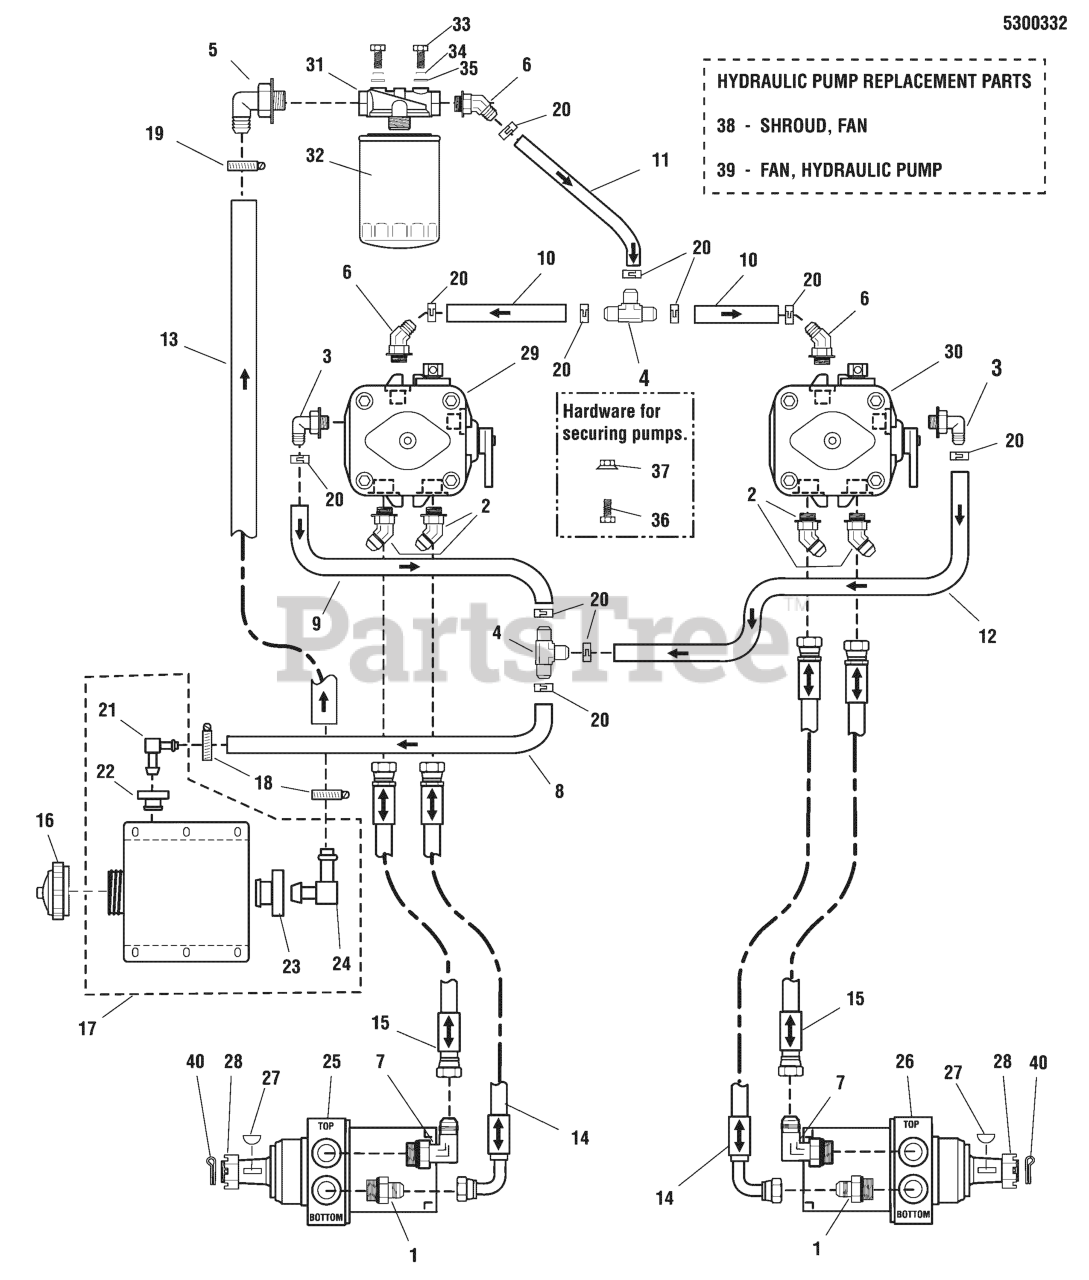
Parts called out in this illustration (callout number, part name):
1	ADAPTER, HYDRAULIC
2	FITTING, #8 JIC - #8 O-RING 45DEG.
3	ADAPTER, 90 DEG. 9/16 - 3/8 BARB
4	FITTING, TEE, 1/2" HOSE
5	ADAPTER, 90 DEG. 9/16 - 5/8 BARB
6	ADAPTER, 45, 9/16 - 3/8 BARB
7	FITTING, #10 ORING-#8 JIC, 90D
8	HOSE, 3/8" PUSH-LOCK, 22.00"
9	HOSE, 3/8" PUSH-LOCK, 6.50"
10	HOSE, 3/8" PUSH-LOCK, 6.00"
11	HOSE, 3/8" PUSH-LOCK, 8.00"
12	HOSE, 3/8" PUSH-LOCK, 23.00"
13	HOSE, 5/8" PUSH-LOCK, 24.00"
14	HOSE ASSEMBLY, (26.50)
15	HOSE ASSEMBLY, 22.50"
16	CAP, HYDRAULIC
17	TANK, HYDRAULIC, ASSEMBLY
18	CLAMP, #4 HOSE, STAINLESS
19	CLAMP, #10 HOSE, STAINLESS
20	CLAMP, HOSE
21	FITTING, ELBOW, 3/8"
22	BUSHING-FUEL TANK RED RUBBER
23	GROMMET
24	FITTING, ELBOW, 5/8"
25	MOTOR,WHEEL,18 CI, LH
26	MOTOR,WHEEL,18 CI, RH
27	KEY
28	NUT, CASTLE, 1-20
29	PUMP, HYD, 12CC - LH, PK-3HBQ-FV1F-XXXX
30	PUMP, HYD, 12CC - RH, PK-3KBQ-FV1F-XXXX
31	FILTER HEAD, HYDRAULIC
32	FILTER, OIL
33	BOLT, 1/4"-20 X 3/4" GD5 YZ
34	WASHER, 1/4 SAE
35	WASHER, 1/4 LOCK
36	BOLT, 3/8-16 X 1-1/4" GD5 CZ
37	NUT, 3/8-16 HEX SERRATED FLANGE
38	SHROUD, FAN
39	FAN, HYD. PUMP
40	PIN, COTTER, 1/8' X 2"
